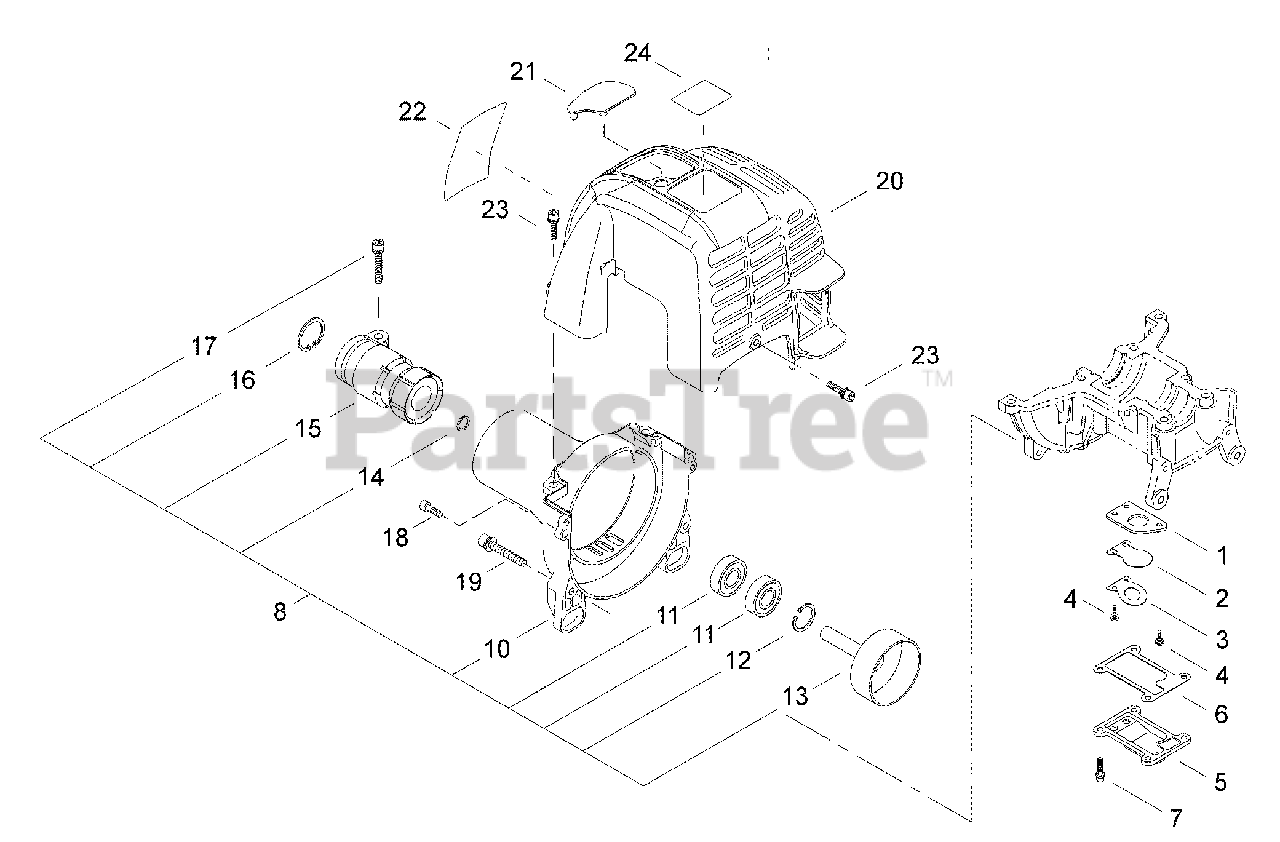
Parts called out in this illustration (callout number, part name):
1	PLATE, REED BACKING
2	VALVE, REED
3	STOP, REED VALVE
4	SCREW - 3X10
5	COVER, REED VALVE
6	GASKET, REED VALVE
7	SCREW - 4X14
8	FAN CASE ASSY
10	CASE, FAN
11	BEARING, BALL - 6001DDUC3
12	RING, RETAINING - 28
13	DRUM, CLUTCH
14	RING, RETAINING
15	CLAMP, MAIN PIPE
16	RING, RETAINING - 42
17	SCREW - 5X22
18	SCREW - 5X16
19	SCREW - 5X40
20	COVER, ENGINE
21	COVER, SPARK PLUG
22	LABEL - C4
23	SCREW - 4X14
24	LABEL - MODEL C3410
